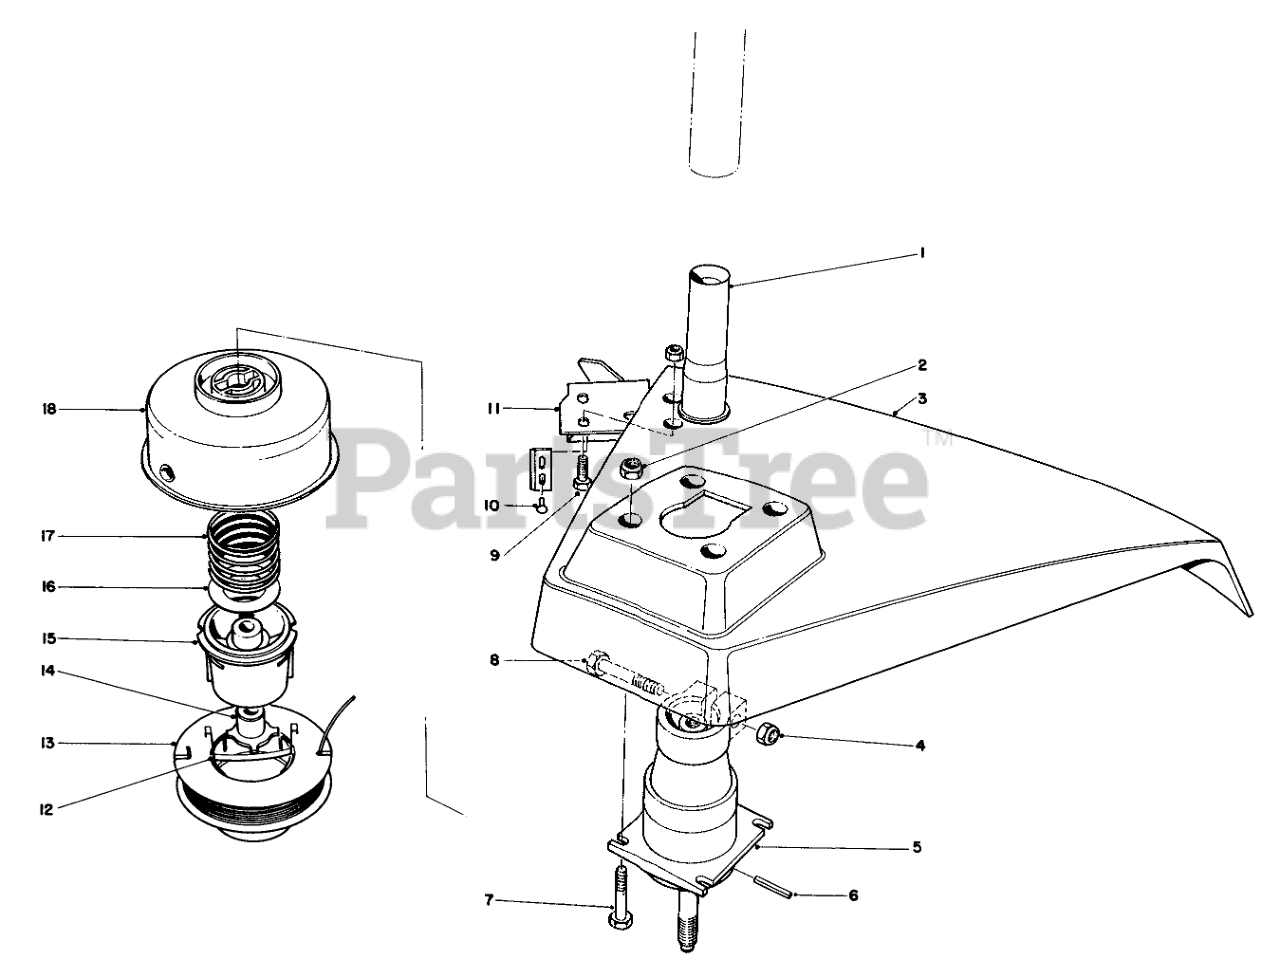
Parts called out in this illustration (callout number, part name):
1	INSERT-POLE END
2	NUT-LOCK, NI
3	Shield
4	NUT-LOCK, NI
5	Bearing Housing Assembly
6	COIL PIN
7	SCREW-HH
8	SCREW-HH
9	SCREW-HWH
10	RIVET-BLIND
11	Knife Blade Assembly (Incl. Ref. #10)
12	SADDLE-SPOOL CAP
13	Empty Spool
14	DRIVER
15	SPOOL CORE
16	WASHER-FLAT
17	SPRING COMPRESSION
18	DRUM/EYELET
